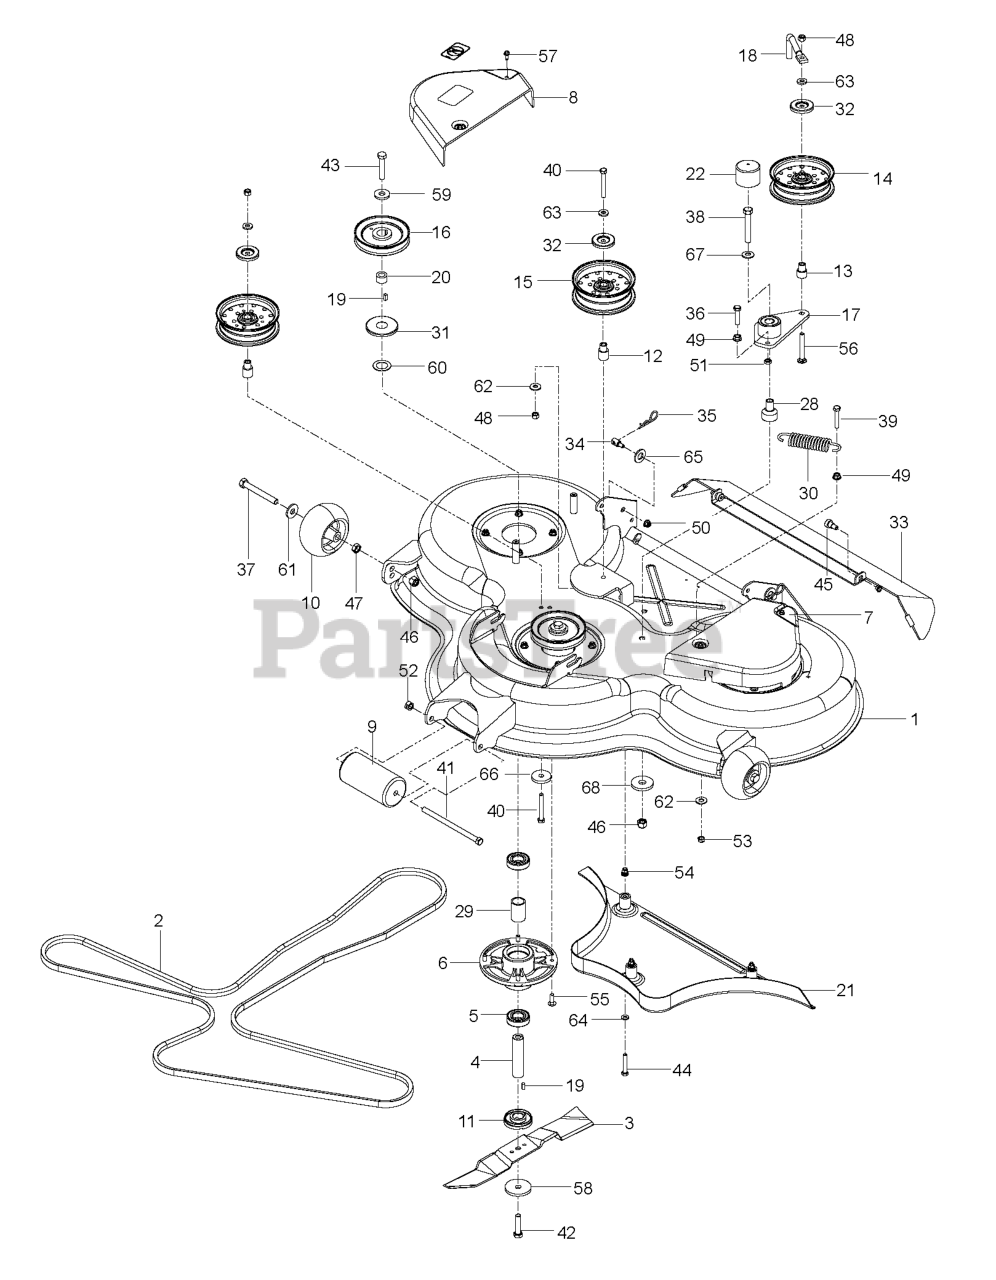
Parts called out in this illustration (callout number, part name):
5	BALL BEARING
6	BEARING HOUSING
7	SHIELD.BELT.LT.48".COMBI-DECK
8	SHIELD.BELT.RT.48".COMBI-DECK
9	ROLLER
10	GAUGE WHEEL
11	BUSHING, BLADE
12	IDLER BUSHING
13	BUSHING, IDLER
14	IDLER PULLEY
15	IDLER PULLEY (TALL)
16	PULLEY, 48
17	ARM-IDLER W/BRG
18	BELT KEEPER 5"
20	KEY RETAINER
22	CAP, VINYL
28	PIVOT, BEARING
31	BOTTOM DUST CAP
32	DUST SHIELD
33	GUARD, DISCHARGE, BLK
34	STUD.FASTNER.W/ANTI-ROTATE
35	HAIRPIN #4
36	HCS 3/8-16 X 1-1/2
37	HCS 1/2-13 X 4 GR 5 ZD
38	SCREW, 1/2C X 3 HEX CAP
39	HCS 3/8C X 2
40	SCREW 3/8C X 2 3/4 HEX CAP
41	HCS 7/16-14 X 7 GR5 ZD
42	HCS M12 X 1.75 X 50 GR8.8 ZD
43	HCS M12 X 1.75 X 60 GR5 ZD
44	HCS M8 X 1.25 X 50 GR8.8 ZD
45	SB 3/8-16 X 3/8 SKT HD ZD
46	NUT 1/2-13 HEX NYLOC ZD
47	NUT 1/2 HEX JAM
48	NUT 3/8-16 NYLOC
49	NUT 3/8C WHIZ
50	5/16-18 NYLOC FLANGE NUT
51	NUT 3/8-16 HEX JAM
52	NUT 7/16C CENTERLOCK
53	NUT HEX 3/8-16 NYLON, THIN
55	RHSNB 5/16C X 1
56	RHSNB 3/8-16 X 2.75
57	SCREW 1/4 X 5/8
59	WASHER-.533IDX1.37OD
60	WASHER-1.06IDX1.63ODX.06
61	WASH USS FLAT 1/2
62	WASHER 3/8 FLAT
63	WASHER, 3/8 THICK
64	FLAT WASHER 5/16 SAE
65	WASHER 5/8 FLAT
66	SPINDLE WASHER
67	CONTACT BELLSPR 1/2
68	WASHER, SUPPORT
